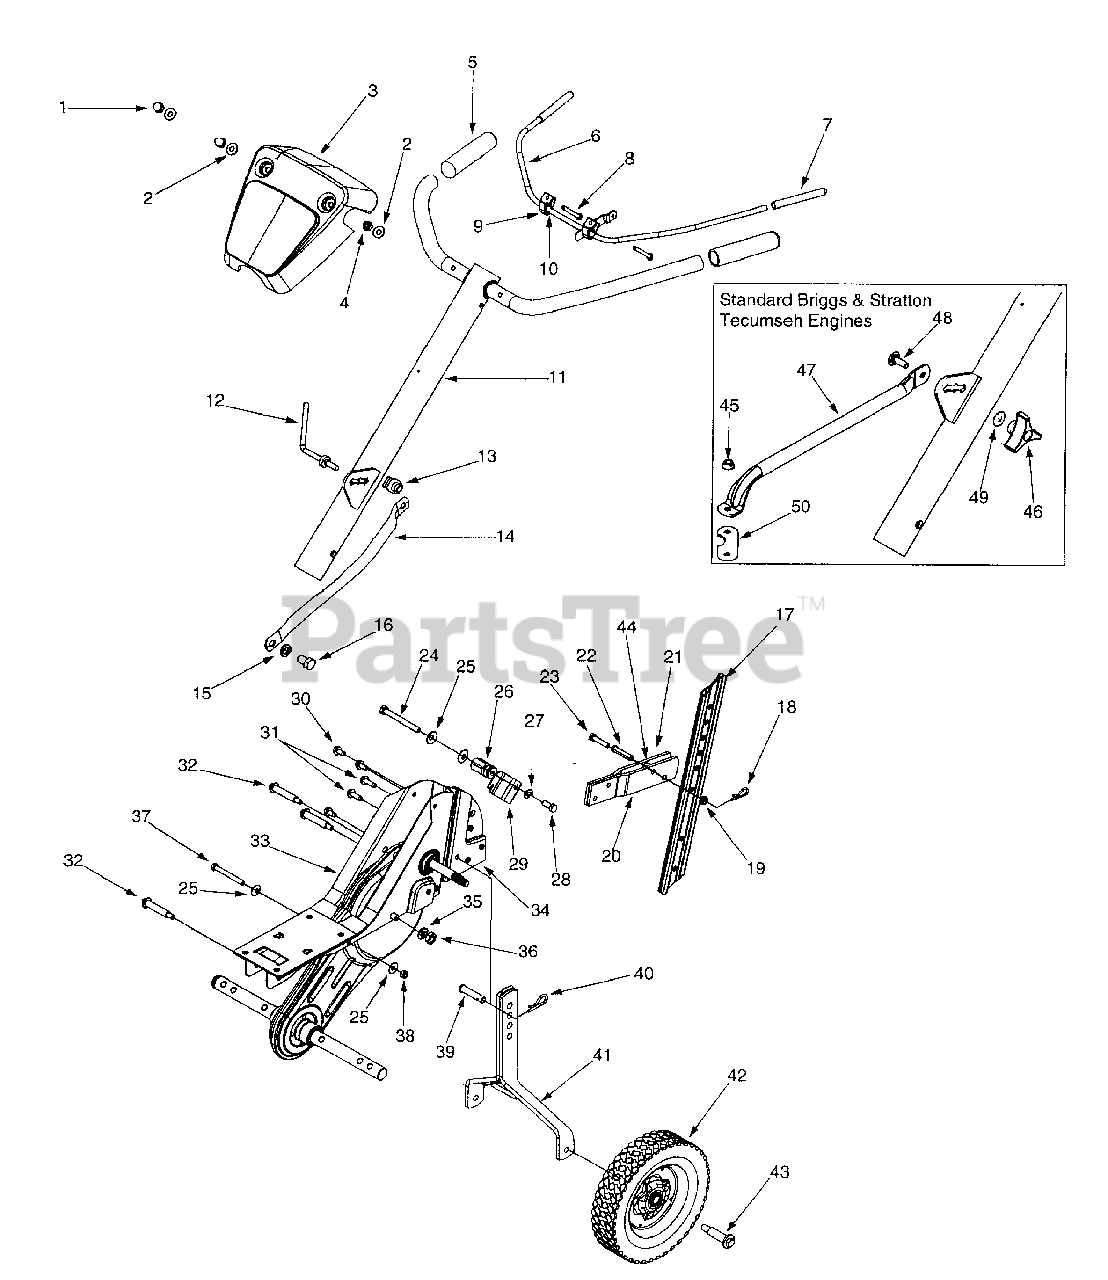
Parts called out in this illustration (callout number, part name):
1	Acorn Lock Nut 1/4-20
2	Flat Washer .271" I.D. x .630" O.D.
3	Handle Cover
4	Hex Nut 1/4-20 Gr.2
5	Grip-Handle
7	Grip-Clutch
8	Hex Bolt 1/4-20 x 2.25" Lg. Gr.5
9	Clutch Handle Holder
10	Flat Washer.385" I.D. x .62" O.D.
13	U Nut 5/16-18
16	Hex Bolt 1/2-20 Gr.
18	Cotter Pin
19	Hex Flange L-Nut 5/16-18
22	Clevis Pin
23	Hex Bolt 5/16-18 x 1.5" Lg.
24	Hex Bolt 5/16-18 x 3" Lg.
25	Wash. Bell. .340" I.D. x .872" O.D.
26	Spec. Hex Nut
27	L-Wash. 5/16" I.D.
28	Hex Bolt 5/16-18 Gr. 5
30	Hex Wash Screw 5/16-18 x .62"
31	Hex Wash. Hd. TT Tap Scr.
32	Shdl. Bolt 5/16-18
35	Lock Washer 7/16
36	Jam Nut 7/16-20 Gr. 2
37	Hex Bolt 5/16-18 x 2.75" Lg.
38	Hex Nyloc Nut 5/16-18 Thd.
39	Clevis Pin
40	Cotter Pin
42	Wheel Ass'y 8" x 1.75"
43	Shoulder Screw.496 x 1.445
44	Spacer
45	Hex Flange L-Nut 5/16-18 Thd. (Gr. 5)
46	Hand Knob
49	Bell. Wash. .34" I.D.
50	Engine Brkt. (Std B&S)
